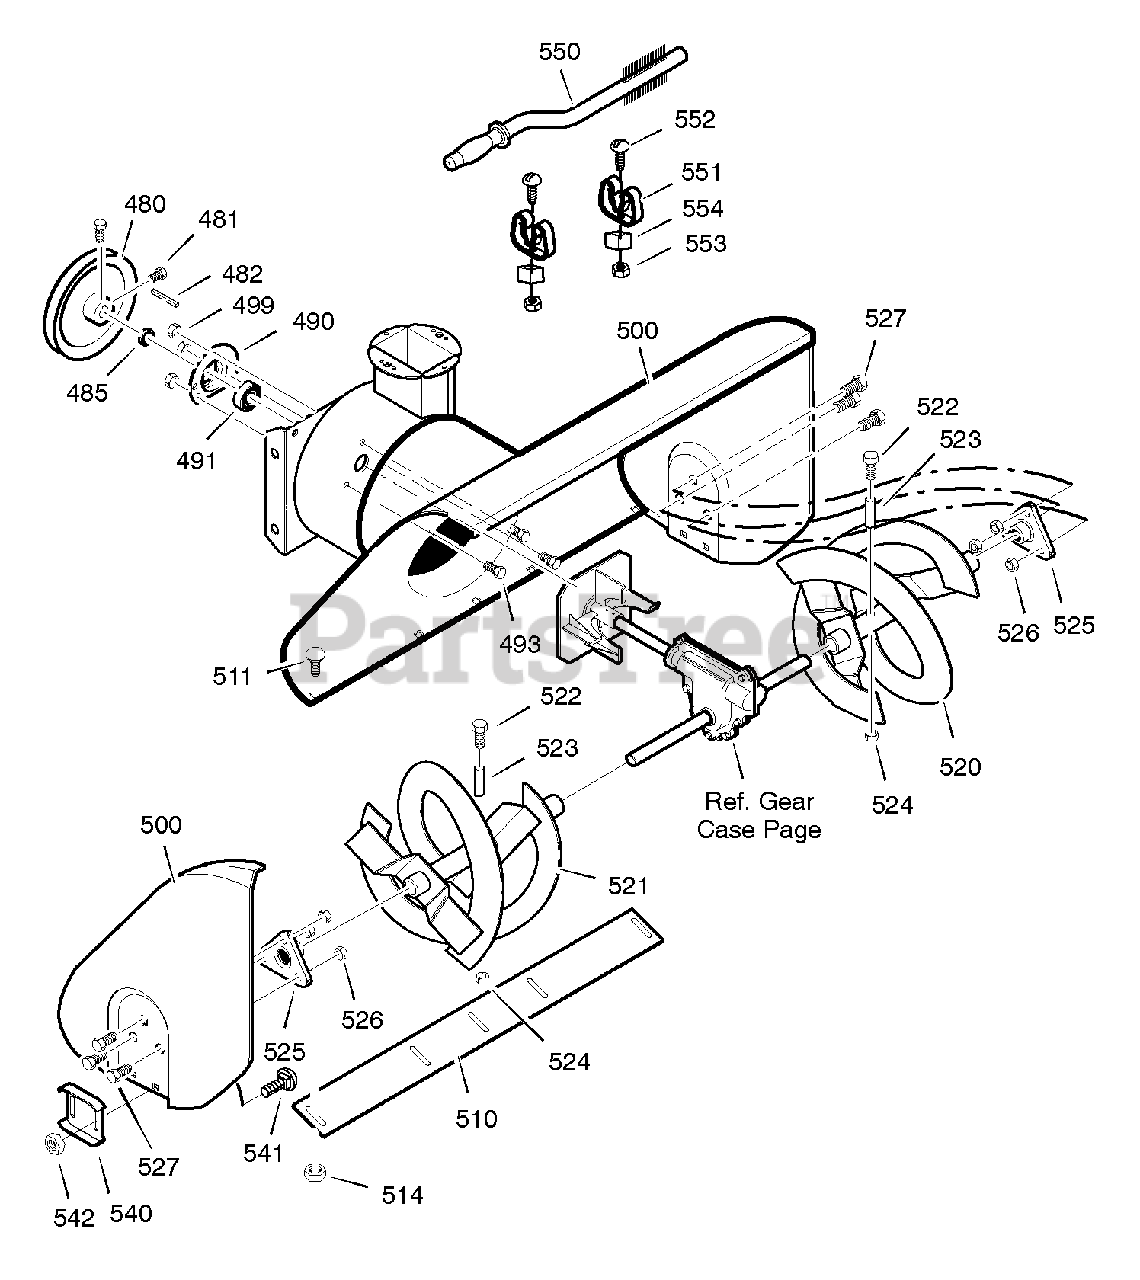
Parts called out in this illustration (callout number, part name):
480	PULLEY, V4L 6.12X0.67
481	SCREW, 5/16-18 x 0.63
482	KEY, SQUARE 3/16 X 3/4
485	SPACER, FRICTION PULLEY
490	RETAINER, BALL BRNG
491	BEARING, BALL
493	BOLT, HEX 5/16-18 X 1/2
499	NUT, 5/16-18 HEXWDFLLK
500	HOUSING, ASSY
510	BLADE, SCRAPER
511	BOLT, 1/4-20 X 3/4
514	NUT, 1/4-20
520	AUGER, ASSY, LH
521	AUGER, ASSY, RH
522	SCREW
523	SPACER, SLEEVE
524	NUT, 1/4-20
525	BEARING, FLANGE
526	NUT, 5/16-18
527	SCREW, 5/16-18 x 3/4
540	SKID, HEIGHT ADJUST
541	BOLT, 5/16-18 X .75
542	NUT, 5/16-18
550	BRUSH, CLEANOUT
551	CLIP, RETAINER
552	SCREW
553	NUT
